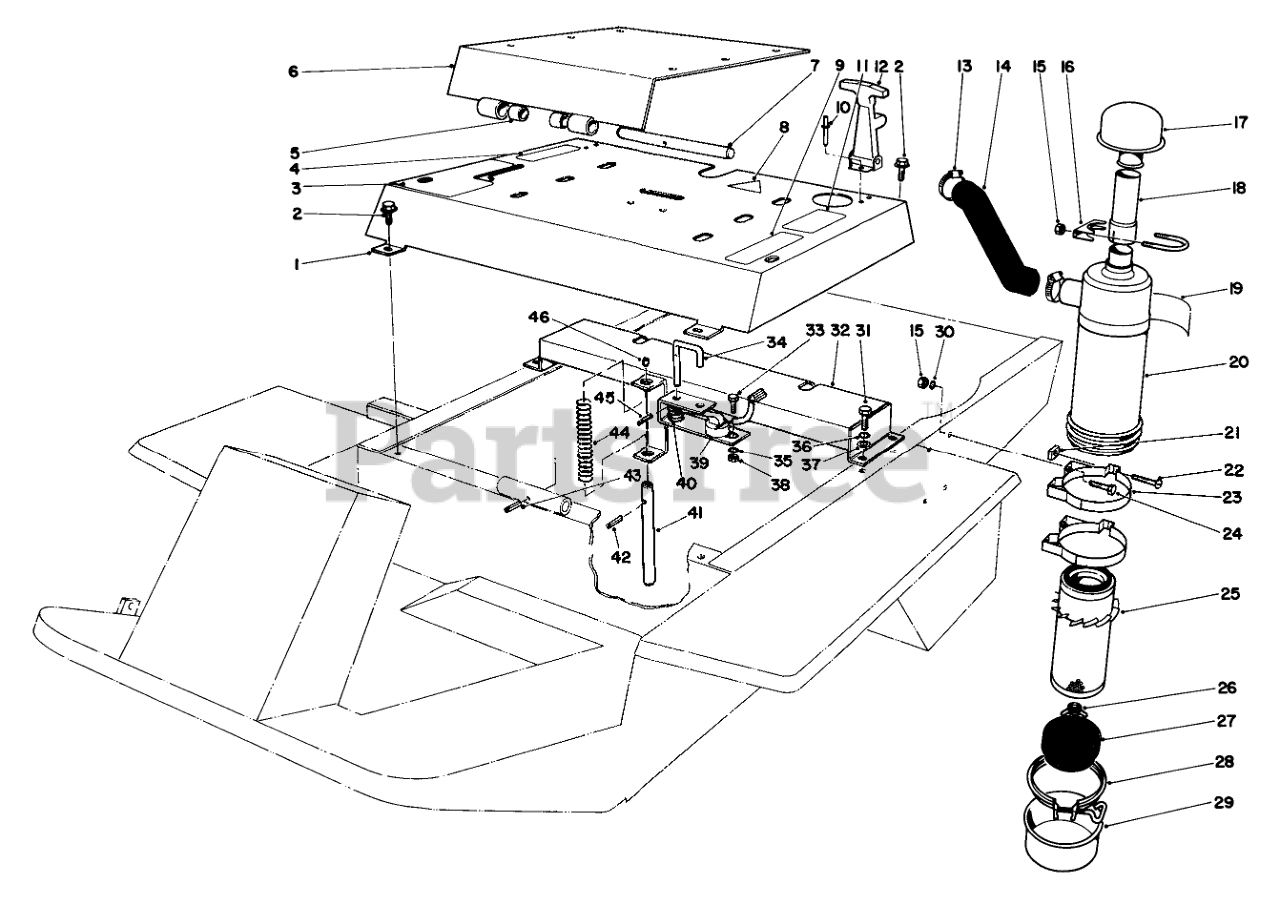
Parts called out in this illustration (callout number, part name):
1	Cover-Seat Support (Incl. Ref. #4, 5, 9 & 10)
2	SCREW-HHFTF
3	Decal Hydraulic Lift
4	Decal Caution
5	.503ID X .875LG BSHG
6	Seat Mounting (Incl. Ref. #6)
7	SHAFT-PIVOT, SEAT
8	DECAL-DANGER
9	Decal Caution
10	NUT-LOCK, NI
11	DECAL-REFUELING
12	Draw Latch
13	CLAMP-HOSE
15	NUT-HEX
16	CLAMP-MUFFLER
18	Tube-Air Cleaner
19	DECAL-INSTALLATION
20	Air Cleaner Assembly (Incl. Ref. #18 & 24-28)
21	NUT-SQUARE
22	SCREW
23	Band Assembly Mounting (Incl. Ref. #20 & 21)
24	SCREW-HH
25	ELEMENT ASM
26	NUT AND GASKET ASM
27	SKIRT-BAFFLE
28	CLAMP ASM
29	A/C CUP ASM
30	WASHER-LOCK
31	SCREW-HH
32	Seat Support
33	SCREW-HH
34	SEAT SWITCH PIN
35	WASHER-LOCK
36	WASHER-LOCK
37	WASHER-FLAT
38	NUT-HEX
39	SWITCH ARM
40	SPRING
41	PIN-SWITCH, SEAT
42	PIN-ROLL, SLOTTED
43	PIN-ROLL, SLOTTED
44	SPRING-COMP
45	PIN-SPRING
46	PIN-PEDAL
